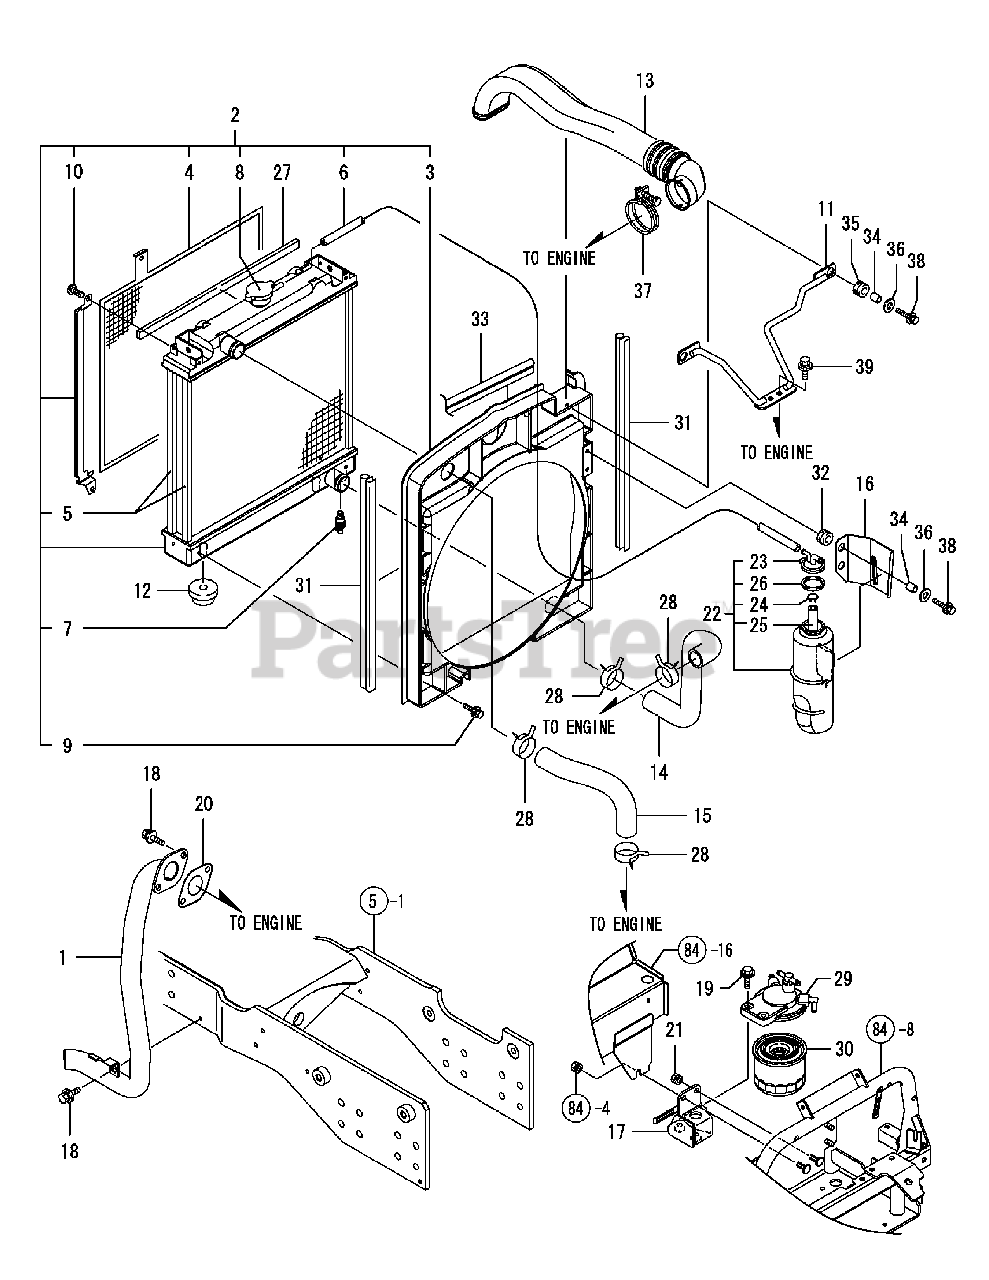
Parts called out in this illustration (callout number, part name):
7	Valve Assy,Drain
8	Cap, Radiator D46
10	Screw M 6X 12,Pan Hd
11	Support Rod Cmp
17	Bracket, Filter Cmp
19	Bolt M 8X 30 Plated
21	Nut W/Washer 8
22	Tank Assy, Sub
29	Bracket, Filter
31	Weather-Strip, 470
33	Rubber, Seal 320
35	Grommet, 10-16
